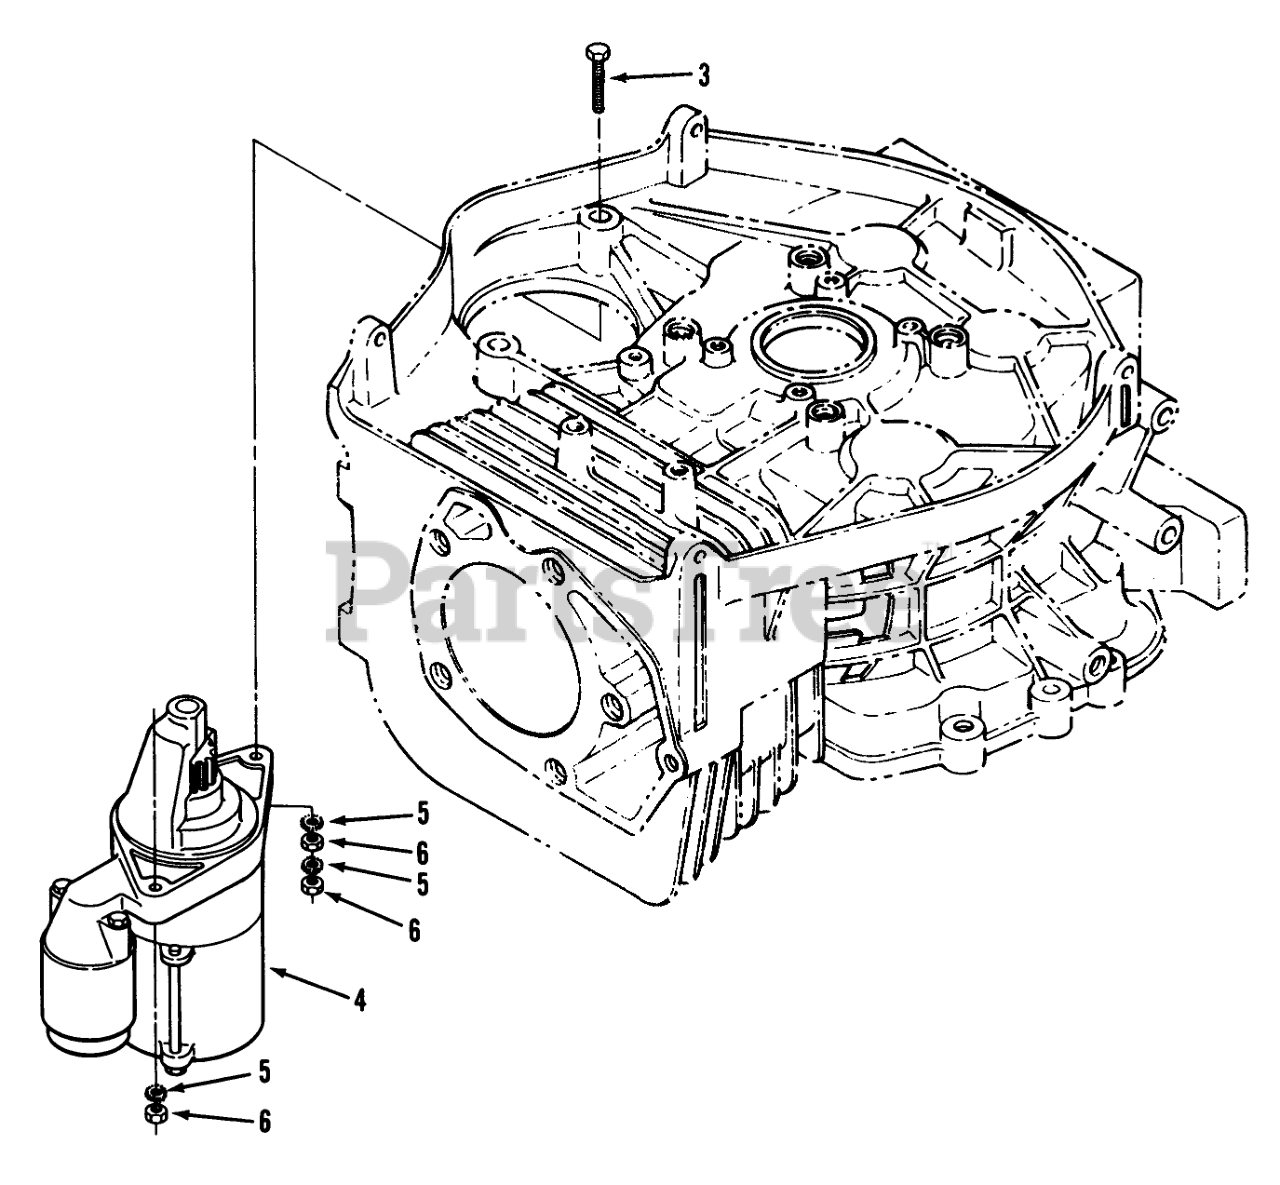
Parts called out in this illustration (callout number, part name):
3	Screw
4	STARTER
5	WASHER
6	Nut
